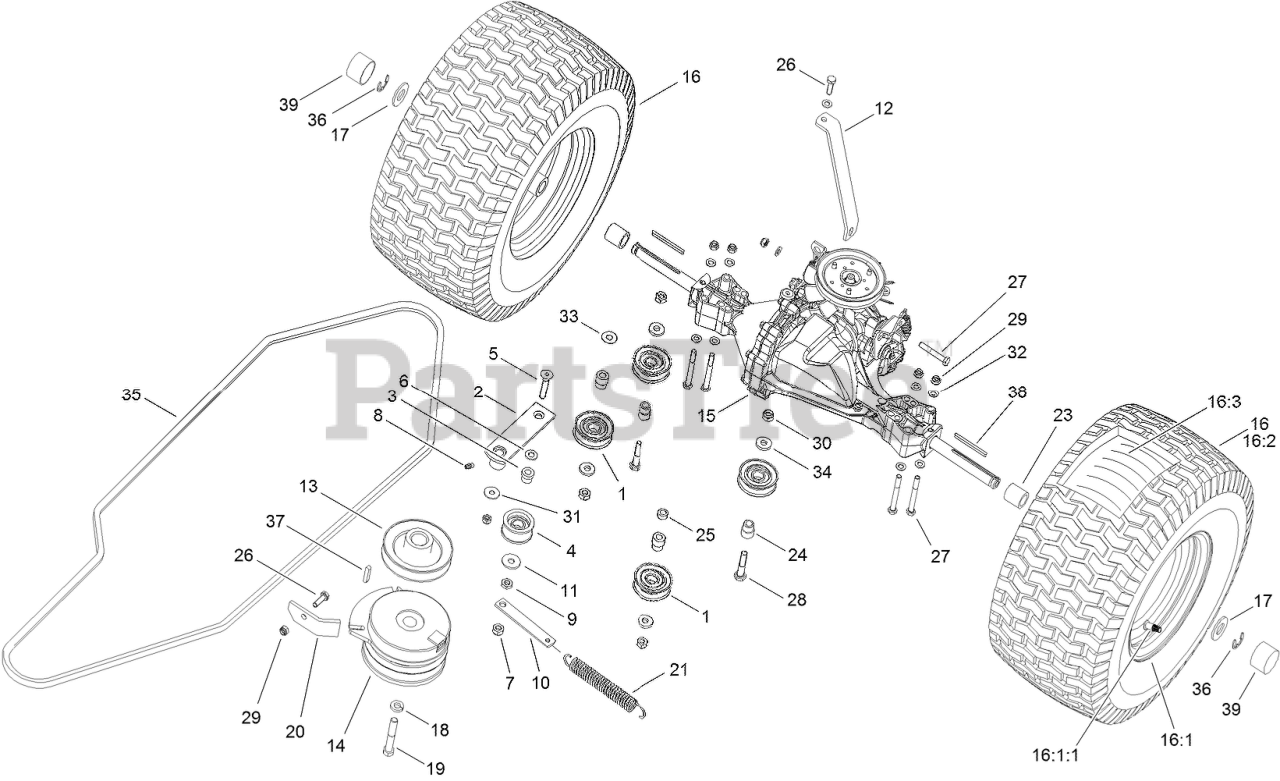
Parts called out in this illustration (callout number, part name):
1	PULLEY-IDLER
2	ARM-IDLER
3	BUSHING-IDLER
4	PULLEY-IDLER
6	WASHER-FLAT
7	NUT-LOCK
8	FITTING-GREASE
9	NUT-HEX
10	BRACKET-TENTION
11	WASHER
12	BRACKET
13	PULLEY-ENGINE
14	CLUTCH-ELECTRIC
15	TRANSMISSION ASM
16	WHEEL ASM
16:1	RIM-REAR
16:1:1	Valve-Tire
16:3	Tube
17	WASHER
18	WASHER-SPRING, BELLEVILLE
19	SCREW-HH
20	BRACKET-RETAINER
21	SPRING
23	SPACER-AXLE
24	BUSHING
25	SPACER
26	SCREW-HH
27	CAPSCREW
28	SCREW-HH
29	NUT-LOCK, NI
30	NUT-LOCK
31	WASHER-PLAIN
32	WASHER-PLAIN
33	Washer
34	WASHER-FLAT
35	V-BELT, TRACTION
36	CLIP-SPRING
37	KEY-SQUARE
38	KEY-SQUARE
39	CAP-HUB
